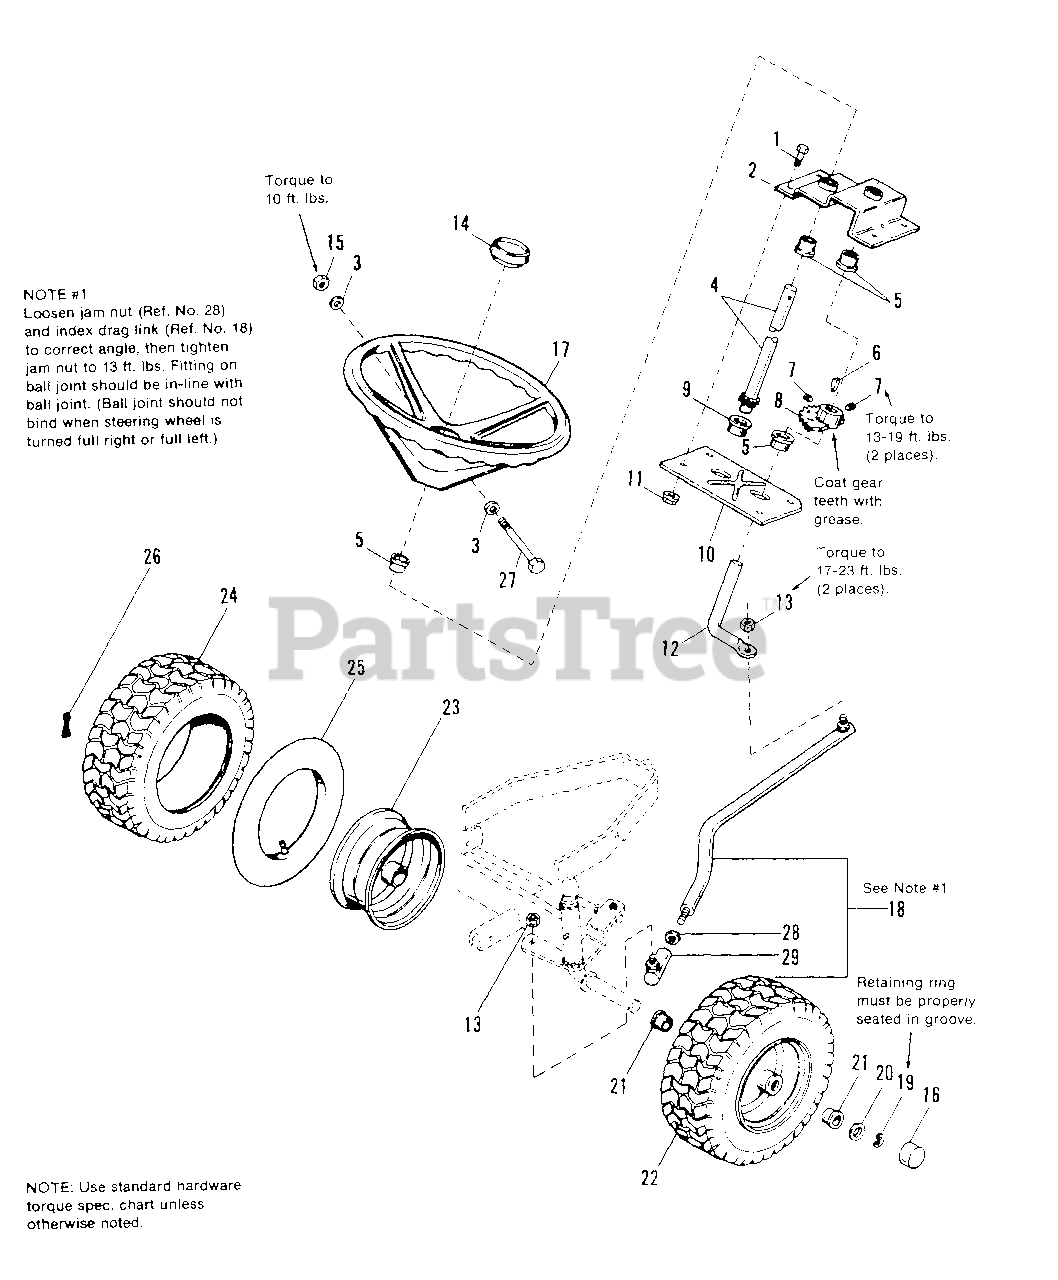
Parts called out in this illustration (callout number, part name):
1	CAPSCREW, 5/16-18 x 3/4
2	PLATE, Steering
3	WASHER, Plain, 5/16
4	SHAFT ASSY., Steering
7	SETSCREW, 5/16-18 x 1/2
8	GEAR, Steering
10	PLATE, Steering
11	LOCKNUT, Hex, Flange, 5/16-18
12	ROD, Steering
13	NUT, Special
14	CAP, Steering Wheel
15	LOCKNUT, 5/16-18
16	CAP, Hub, Thrd.
17	WHEEL, Steering
18	LINK, Drag (Incl. Ref. Nos. 28 & 29)
19	KLIP RING, Ext. 3/4
22	WHEEL & TIRE ASSY., 15 x 6.00-6 (Incl. Ref. Nos. 21, 23, 24, 25 & 26)
23	WHEEL
24	TIRE, 15 x 6.00-6 (Carlisle)
25	TUBE, 4.10/3.50-6
26	STEM, Valve & Cap
27	BOLT, Hex 5/16-18 x 3-1/2
28	JAM NUT
